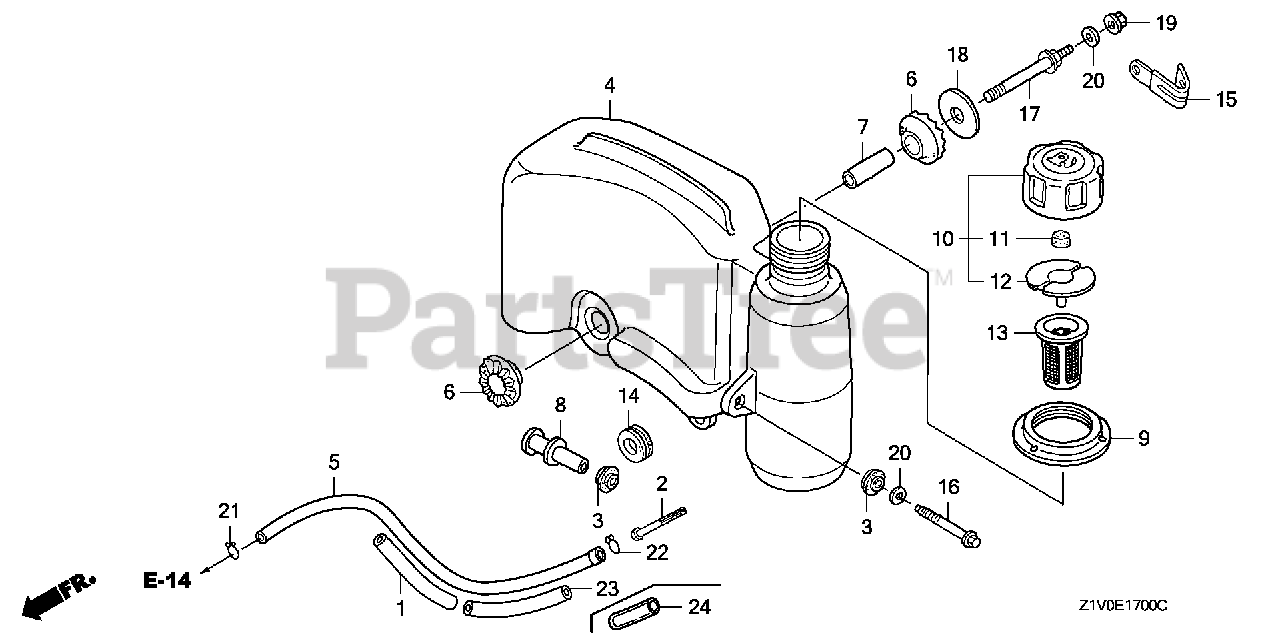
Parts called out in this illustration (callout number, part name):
1	RUBBER, SUPPORTER (107MM)
2	FILTER, FUEL
3	RUBBER, TANK SETTING
4	TANK, FUEL
5	TUBE, FUEL
6	RUBBER B, TANK MOUNTING
7	COLLAR, TANK SET
8	COLLAR, TANK
9	RUBBER, TANK MOUNTING
10	CAP ASSY., FUEL TANK
11	SPONGE, FUEL CAP BREATHER
12	GASKET, FUEL CAP
13	GAUGE, FUEL LEVEL
14	CUSHION, RR. FENDER
16	BOLT, FLANGE (6X47) (CT200)
17	BOLT, TANK STAY
18	WASHER, TANK MOUNTING
19	NUT, FLANGE (6MM)
20	WASHER, PLAIN (6MM)
21	CLIP, TUBE (B8)
22	CLIP, TUBE (C11)
23	RUBBER, SUPPORTER (107MM)
